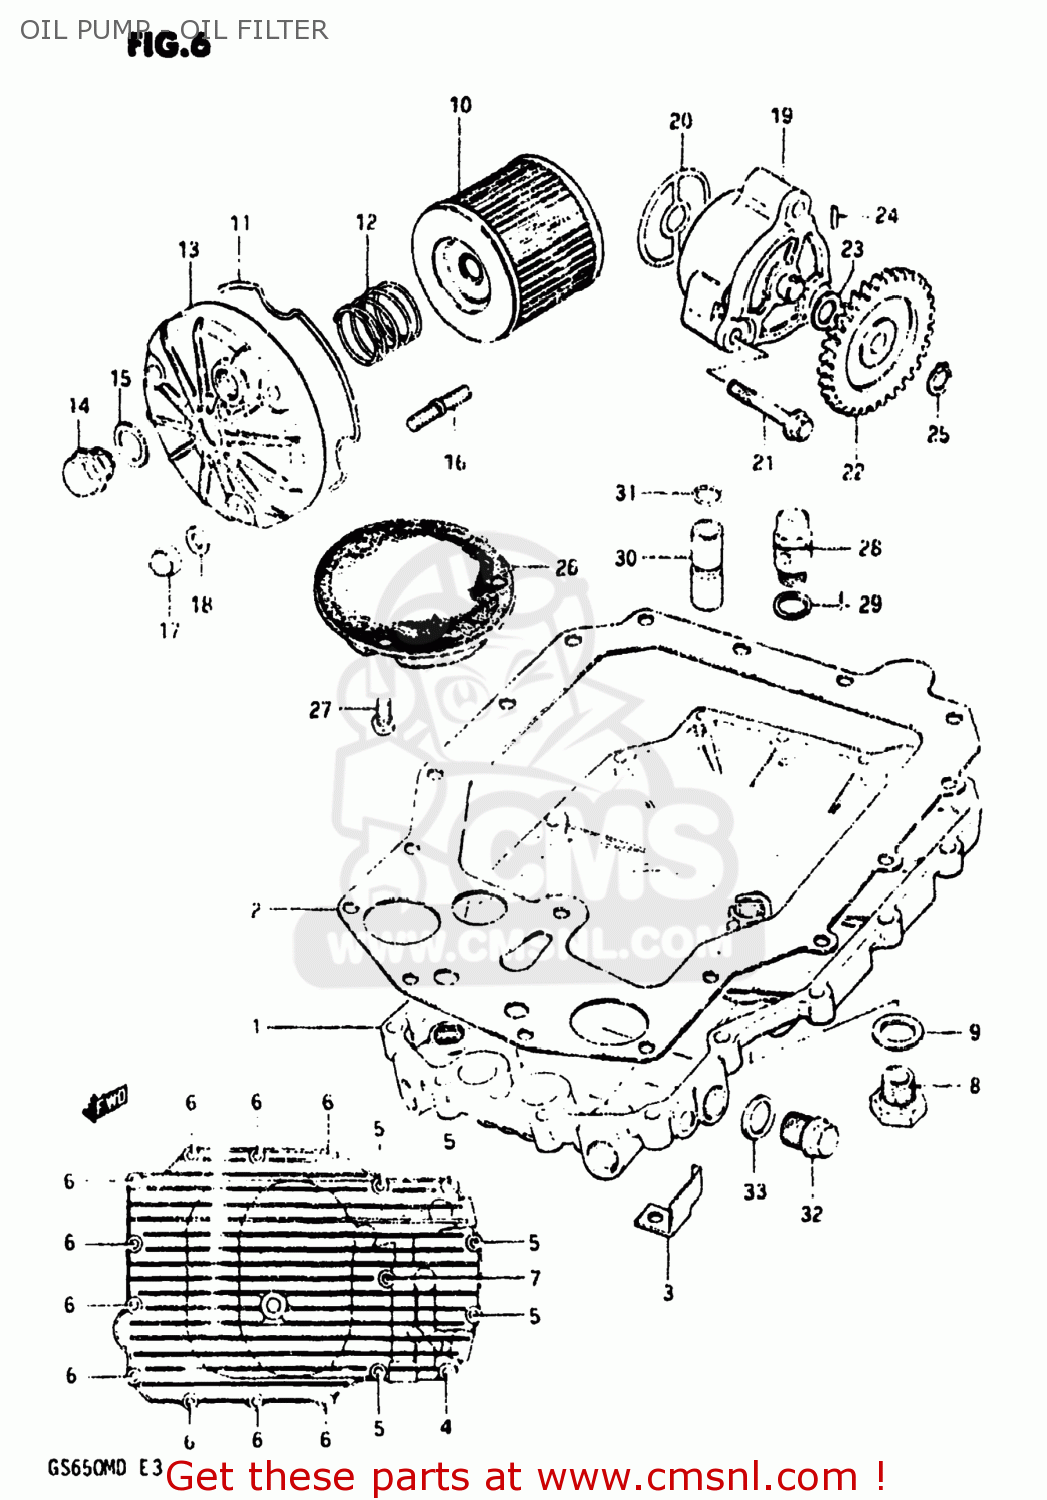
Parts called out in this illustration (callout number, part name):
1	PAN,OIL
2	GASKET,OIL PAN (MCA)
4	BOLT(6X35)
5	BOLT 6X30
6	BOLT
7	BOLT
8	PLUG
9	GASKET(14X19.2X2) (NAS)
10	FILTER ASSY,ENGINE OIL
11	O RING,OIL FILTER CHAMBER CAP
12	SPRING
13	CAP,OIL FILTER
14	PLUG (14X12)
15	GASKET(14X19.2X2) (NAS)
16	STUD 6X20
17	NUT 6MM
18	WASHER
19	PUMP ASSEMBLY,ENGINE OIL
20	O-RING,OIL PUMP
21	BOLT
22	GEAR,ENG OIL PUMP DRIVEN(NT:33
23	SHIM
24	PIN(4X15.8)
25	CIRCLIP
26	STRAINER,ENGINE OIL
27	SCREW 6X12
28	VALVE ASSEMBLY,OIL RELIEF
29	WASHER
30	BY-PASS,OIL REGULATOR
31	O-RING
32	PLUG
33	GASKET(16X22X2) (NAS)
